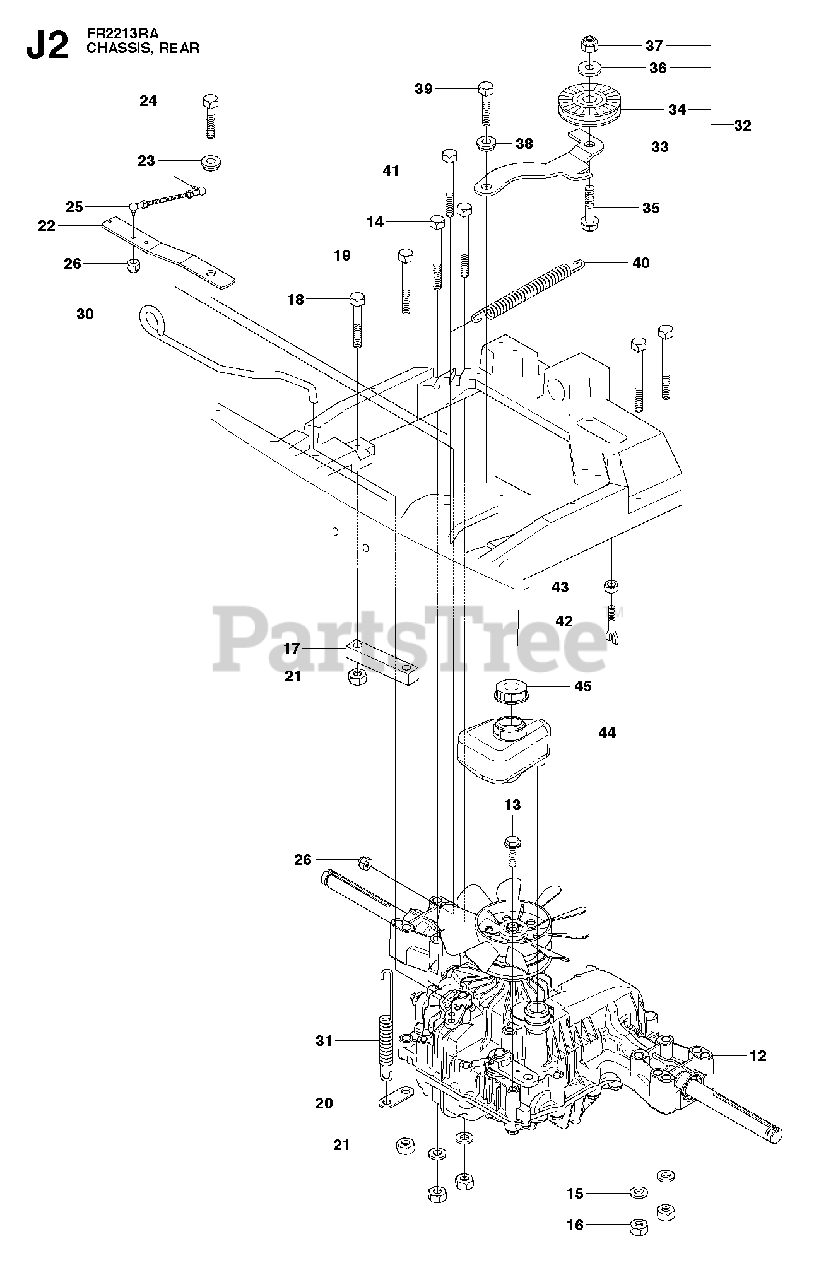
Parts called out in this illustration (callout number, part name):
12	HYDROSTAT
15	WASHER BRB 8.4X17
16	NUT
20	CONNECTOR
21	NUT
23	WASHER
24	SCREW 8X20
26	LOCKNUT M5
31	SPRING
32	TENSIONER
33	TENSIONER
34	PULLEY
35	SCREW
36	SPACER
37	LOCKNUT M8
38	WASHER
39	SCREW 8X20
